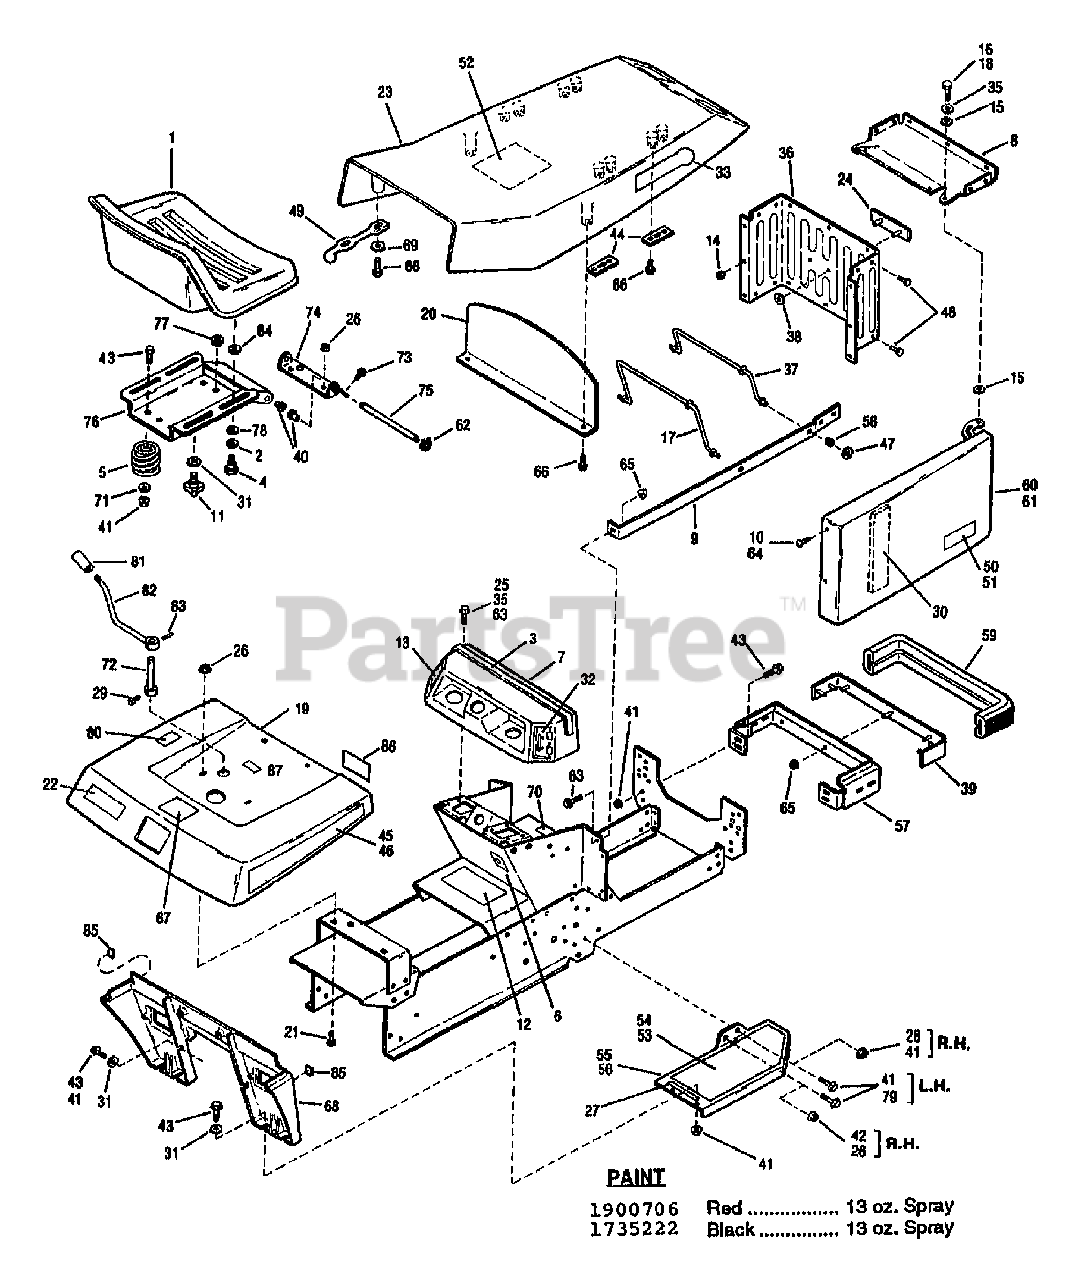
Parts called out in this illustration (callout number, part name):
2	WASHER-1.06X.51X.09 NYLON
3	PAD-HOOD
4	SCR-SHLDR 3/8-16X.25 G5ZP
5	SPRING-COMPRESSION
6	DECAL-IGNITION
7	PANEL-INST
8	CAP-GRILLE
9	SUPPORT
10	NUT-SPEED #10
12	DECAL-OPERATING INST
13	DECAL-CHOKE
14	NUT W/LKWASHER 10-24 ZP
15	WASHER
16	SCR-HH 1/4-20X.75 G5 ZP
17	LINK-HINGE
18	NUT-HT LK 1/4-20
20	BAFFLE-HOOD
21	BOLT-CARR 5/16-18X.63 ZP
22	DECAL-LOGO FENDER
23	HOOD-TRACTOR
24	PLATE-LOGO
25	NUT-HF/LK 1/4-20 ZP
26	NUT-HFLK 5/16-18 ZP
27	CUSHION
28	SCR-HH 3/8-16X.75 G5 ZP
29	SCR-SQHD 1/4-20X1/2 GR5 (13062 ONLY)
30	BLOCK-SEALING
31	WASHER-.986X.437X.083 ZP
32	DECAL-THROTTLE
33	DECAL-LOGO
35	WASHER-FLAT 1/4 SAE
36	GRILLE-TRACTOR
37	LINK-HINGE
38	NUT-PUSH
39	ASSM-BUMPER STRAP
40	BEARING-FLANGE
41	NUT-HFLK 3/8-16 ZP
42	SCR-TRUSS HD 5/16-18X.62
43	SCR-HFLK 3/8-16X1.00 ZP
44	RETAINER-HINGE LINK
45	DECAL-FENDER RH {13060}
45	DECAL-FENDER RH {13062}
46	DECAL-FENDER LH {13060}
46	DECAL-FENDER LH {13062}
47	RETAINER
48	RIVET-POP
49	LATCH-RUBBER
50	DECAL-SIDE COVER LH
51	DECAL-SIDE COVER RH
52	DECAL-SERVICE INST
53	PAD-FOOTREST LH
54	PAD-FOOTREST RH
55	FOOTREST-LH
56	FOOTREST-RH
57	ASSM-GRILLE SUPT
58	GROMMET
59	BUMPER-EXTRUSION
60	COVER-SIDE LH
61	COVER-SIDE RH
62	RING-RET."E" .300 ID
63	SCR-HH 1/4-20X.625
64	SCR-TRUSS #10-24 X 5/8
65	NUT-HF/LK 1/4-20 ZP
66	SCR-SEMS MACH
67	DECAL-FUEL
68	SUPT-RUNNING BOARD
69	DECAL-FUEL
70	DECAL-WARNING
71	WASHER-FLAT 1.25X.406X.179
72	SHAFT-SHIFT LEVER
73	SCR-HFLK 5/16-18X.75 ZP
74	BRACKET
76	ASSM-SEAT SUPPORT
78	WASHER-BOW .74X.52X.01
81	KNOB-SHIFT LEVER {13062}
82	LEVER-SHIFT {13062}
83	PIN-ROLL .188X1.0 {13062}
84	WASHER-FLAT
85	BUTTON-RUBBER
86	DECAL-U.S.A.
87	DECAL-SOUND LEVEL
